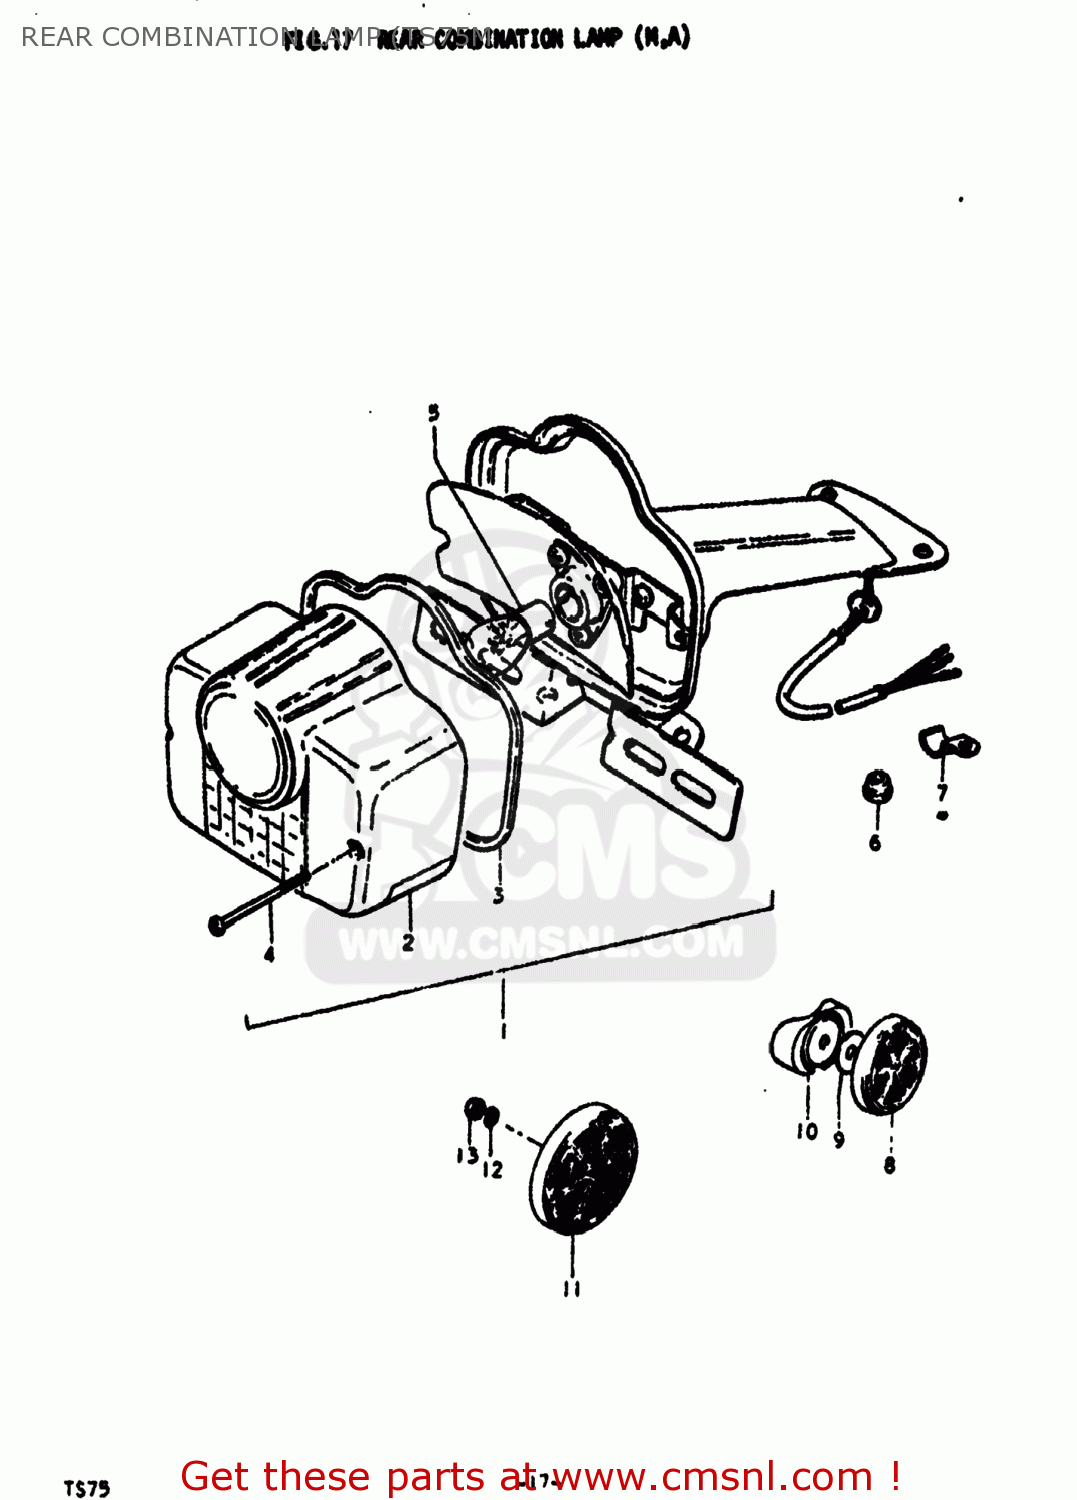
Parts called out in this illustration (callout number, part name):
1	LAMP ASSEMBLY,REAR COMBINATION
2	LENS,REAR COMBINATION LAMP
3	GASKET (NAS)
4	SCREW
5	BULB(6V32/3CP,STANLEY)
6	GROMMET
7	CLAMP
8	REFLEX REFLECTOR ASSEMBLY
9	WASHER
10	SPACER
11	REFLECTOR,REFLEX
12	LOCK WASHER
13	NUT
